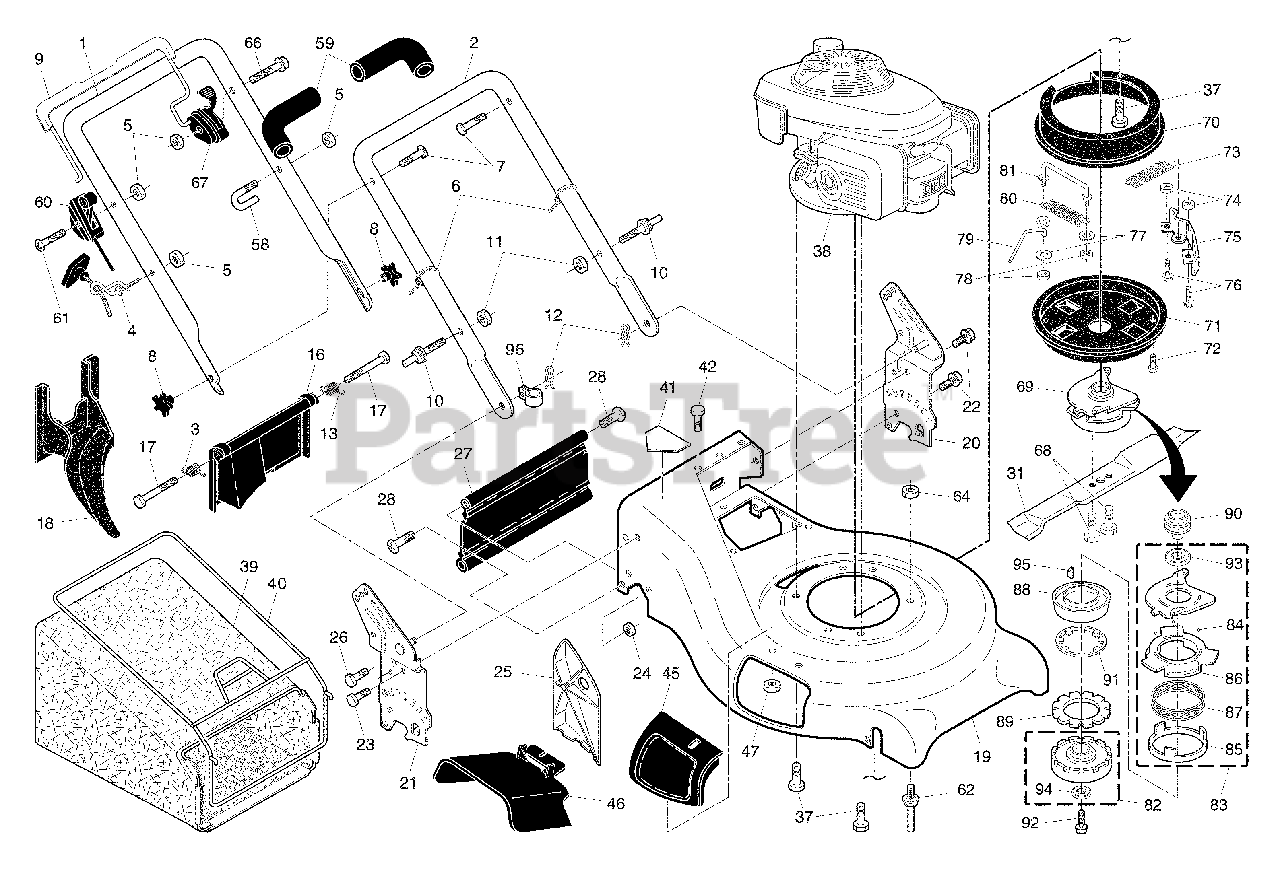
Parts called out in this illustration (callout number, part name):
1	Handle, Upper
2	Handle, Lower
3	Spring, Rear Door, RH
4	Guide, Rope, Side
5	Nut, Hex Lockwasher Insert 1/4-20
6	Wire, Tie
7	Bolt, Handle 5/16-18 x 1.75
8	Knob, Handle
9	Bar, Control, Auto-Walk
10	Bolt, Carriage
11	Nut, Hex, Centerlock 5/16-18 UNC
12	Cotter, Hairpin
13	Spring, Rear Door, LH
16	Rear Door Assembly
17	Bolt, Rear Door
18	Plug, Mulcher
19	Kit, Housing
20	Handle Bracket Assembly, LH
21	Handle Bracket Assembly, RH
22	Screw, Hex Washer Head
23	Bolt, Hex Head 5/16-18 x 5/8
24	Nut, Hex, with Lock Washer Insert 5/16-18
25	Baffle, Side
26	Screw 12 x 5/8
27	Skirt, Rear
28	Screw, Hinge 1/4-20 x 1.25
31	Blade, 21"
37	Bolt, Engine
39	Grassbag
40	Frame, Grassbag
41	Danger Decal
45	Mulcher Door Assembly
46	Deflector, Discharge
59	Grip, Handle, Foam, Smooth
60	Throttle / Engine Control
61	Screw, Hex Head 1/4-20 x 2-1/8
62	Belt Guide, Stud
64	Nut, Hex 3/8-16
66	Screw, Hex Washer Head 1/4-20 x 1/2
67	Blade Brake / Clutch Control
68	Bolt, Hex Head
69	Blade Brake / Clutch
70	Belt Cover, Upper
71	Belt Cover, Lower
72	Screw, Tapping, Hex Washer Head
74	Nut, Hex, Centerlock, Zinc Plated 1/
75	Bracket
76	Bolt, Hex Cap Head 1/4-20 x 5/8
77	Washer, Flat
78	Nut, Hex 3/8-16
79	Belt Keeper
81	Link, Torque
82	Holder Assembly, Blade
83	Plate Assembly, Ball Control
84	Ball, Steel
85	Plate, Spring Hook
86	Plate, Brake
87	Spring, Ball Plate
88	Disk, Drive
89	Disk, Driven
90	Pulley, Drive
91	Spring, Clutch
92	Bolt, Flange (10 x 24)
93	Bearing, Radial Ball (6006)
94	Bearing, Radial Ball (6204)
95	Key, Woodruff (16 x 15)
96	Clip, Cable
